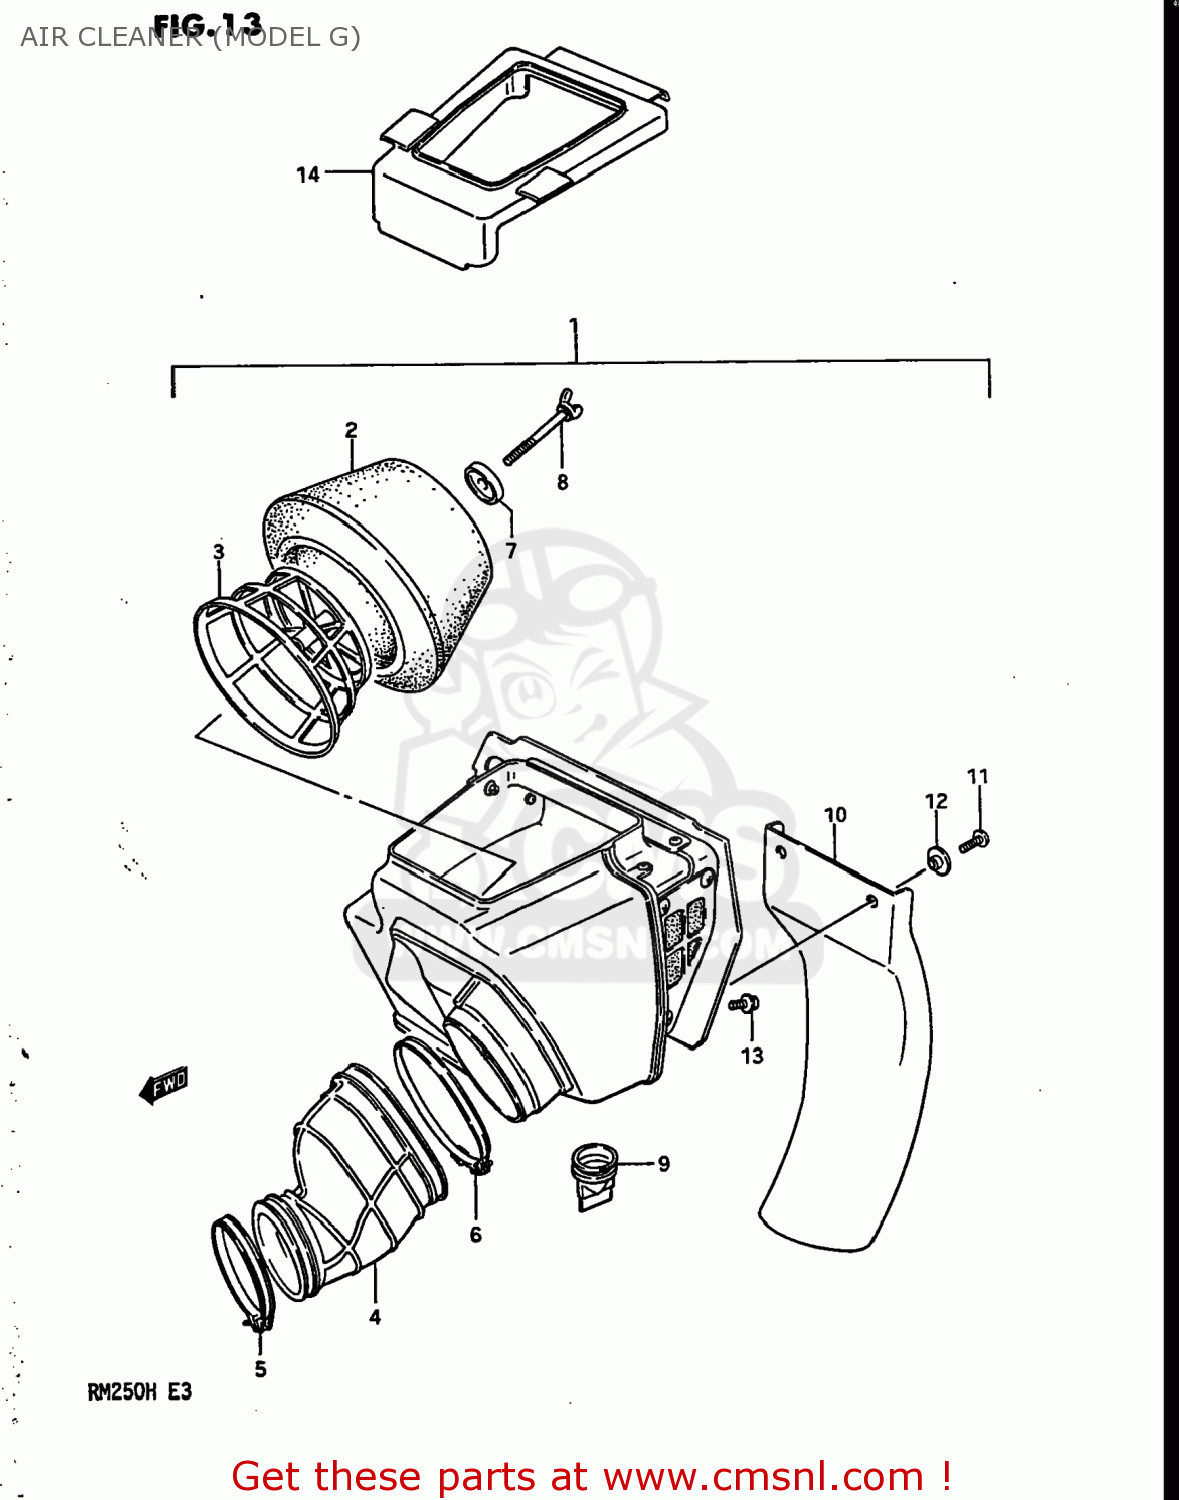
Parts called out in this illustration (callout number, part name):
1	CLEANER ASSEMBLY,AIR
2	FILTER
3	HOLDER,FILTER
4	TUBE,AIR CLEANER OUTLET
5	CLAMP
6	CLAMP
7	WASHER,AIR CLEANER
8	BOLT,WING
9	HOSE,AIR CLEANER DRAIN
10	GUARD,MUD
11	SCREW
12	COLLAR
13	BOLT
14	GUARD,MUD
